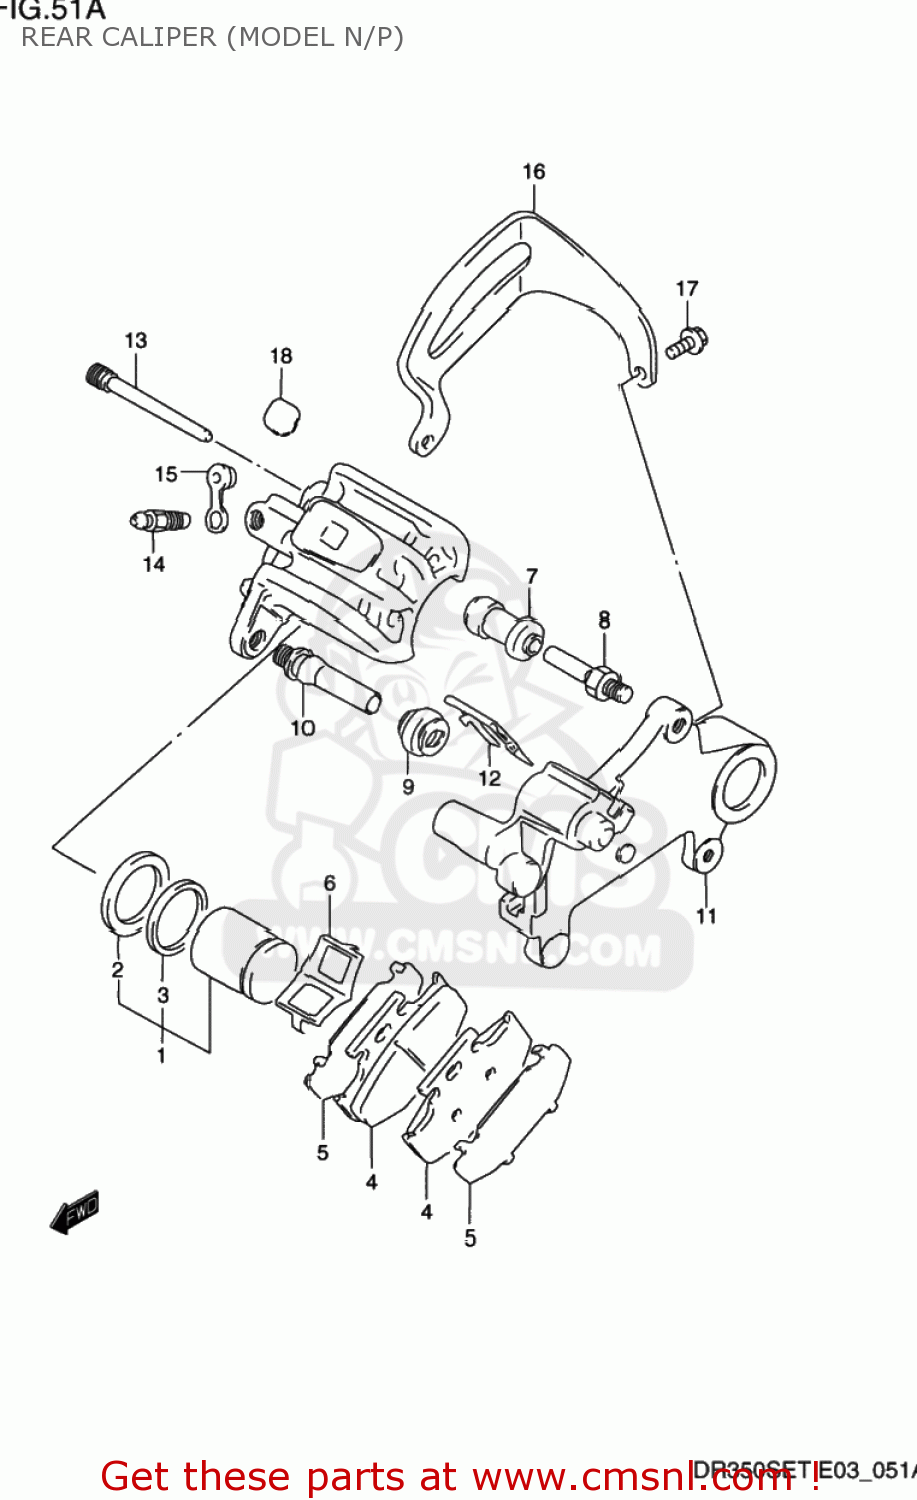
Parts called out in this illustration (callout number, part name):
1	PISTON SET
2	SEAL,PISTON
3	SEAL
4	PAD (MCA)
5	SHIM
6	SPRING,PAD
7	BOOT
8	PIN,BOLT
9	BOOT
10	PIN
11	BRACKET
12	RETAINER,BRACKET
13	PIN,HANGER
14	BLEEDER
15	CAP,BLEEDER
16	GUARD,RR CALIPER
17	BOLT
18	COVER,RR CALIPER BODY
